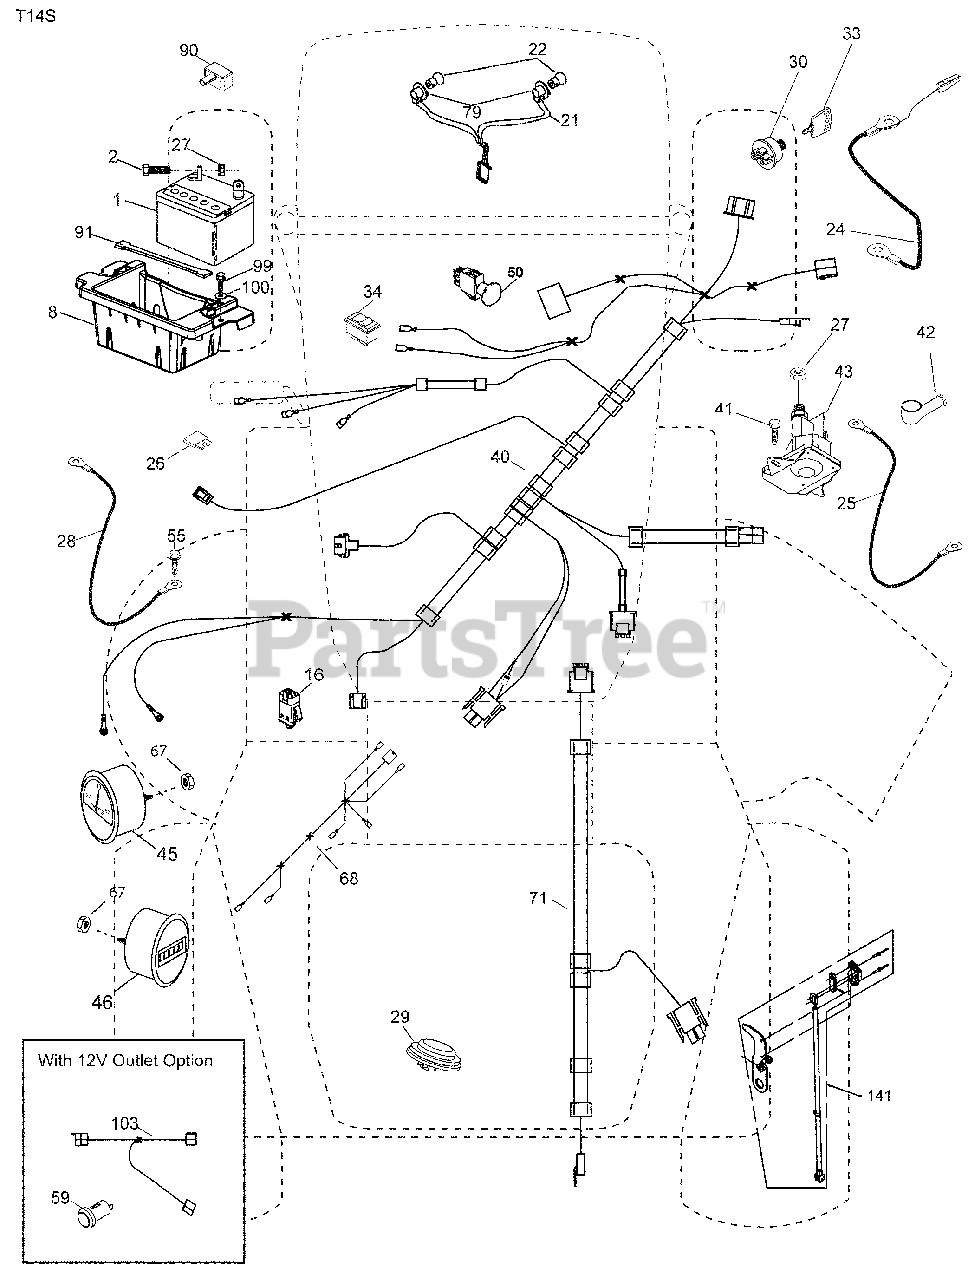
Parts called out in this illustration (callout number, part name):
1	Battery
2	Bolt Hex Head 1/4-20 x 3/4
8	Box Battery
16	Switch Interlock Push-In
21	Harness Socket Light w/4152J
22	Bulb, Light
24	Cable Battery
25	Cable Start Red 17.5"
27	Nut Keps Hex 1/4-20 unc
28	Cable, Ground
29	Switch, Seat
30	Switch Ignition
34	Switch Light/Reset
40	Harness Ign Dash
41	Screw Thd Cut 1/4-20 x 1/2
42	Cover Terminal
43	Solenoid
45	Ammeter Gauge Round Snap-in
46	Gauge Hourmeter
50	Switch, PTO
55	Screw Thdrol 5/16-18 x 3/4 TYTT
59	Outlet 12-Volt
68	Harness Jumper
71	Harness Ignition, Chassis
79	Bulbholder Asm. Incandescent
90	Cover Terminal Battery
91	Strap Battery Mount Front
99	Screw Hexwsh Thdrol 1/4-20 x 3/4
100	Washer 9/32 x 7/8 x 16 Ga.
103	Harness Pigtail 12V Outlet
141	Kit G700/G730 ROS
